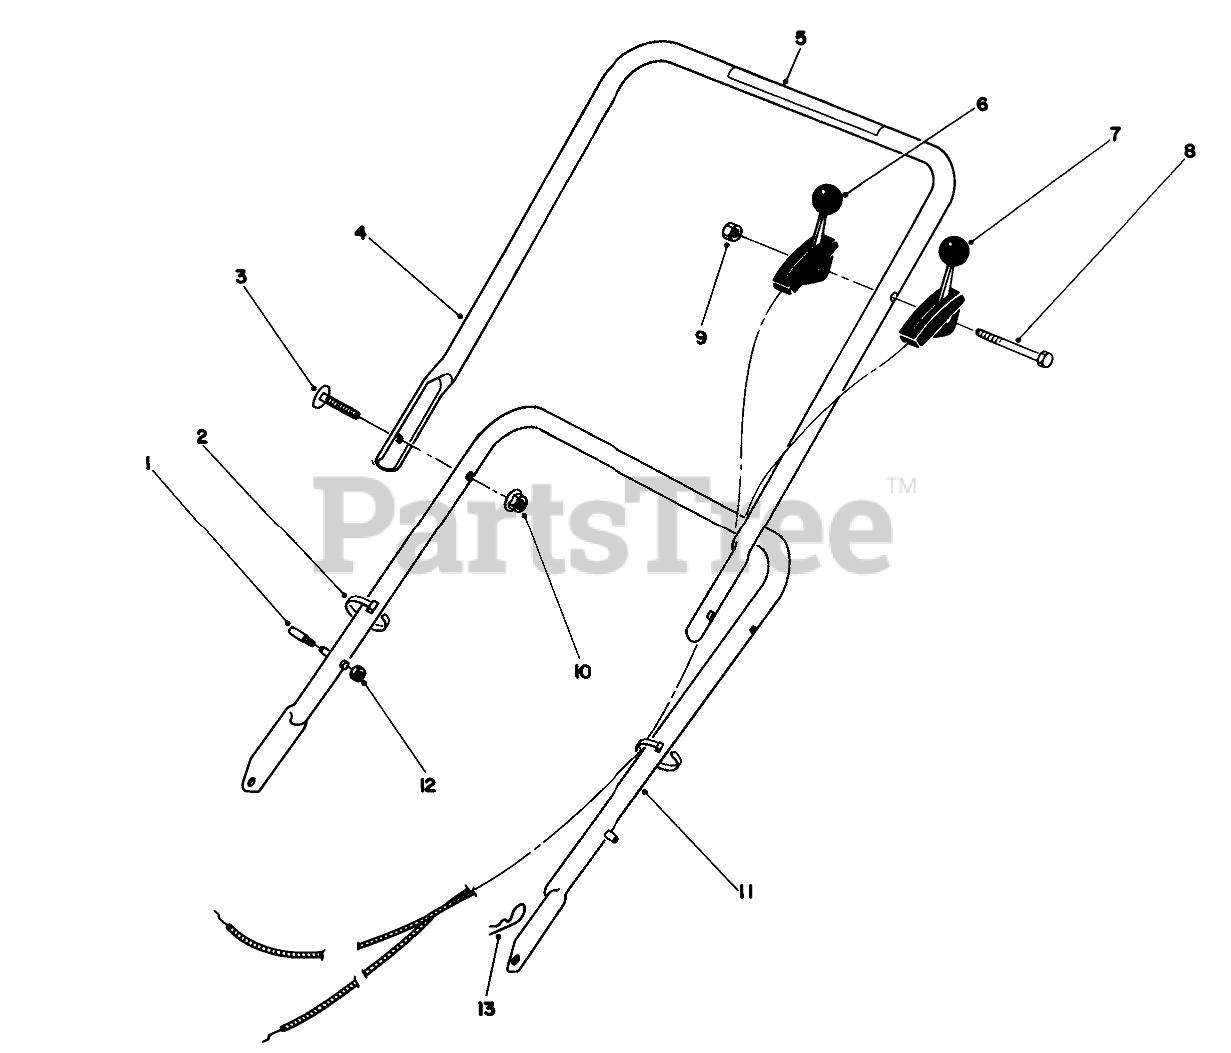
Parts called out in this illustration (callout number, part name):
1	HANDLE PIN
2	TIE-CABLE
3	SCREW
4	Handle-Upper (Incl. Ref. #5)
5	DECAL - HANDLE
6	TRACTION CONTROL
7	THROTTLE CONTROL
8	SCREW-HH
9	NUT-LOCK, NI
10	NUT-LOCK, NI
11	LOWER HANDLE ASM
12	NUT-LOCK, NI
13	PIN-COTTER, HAIR
